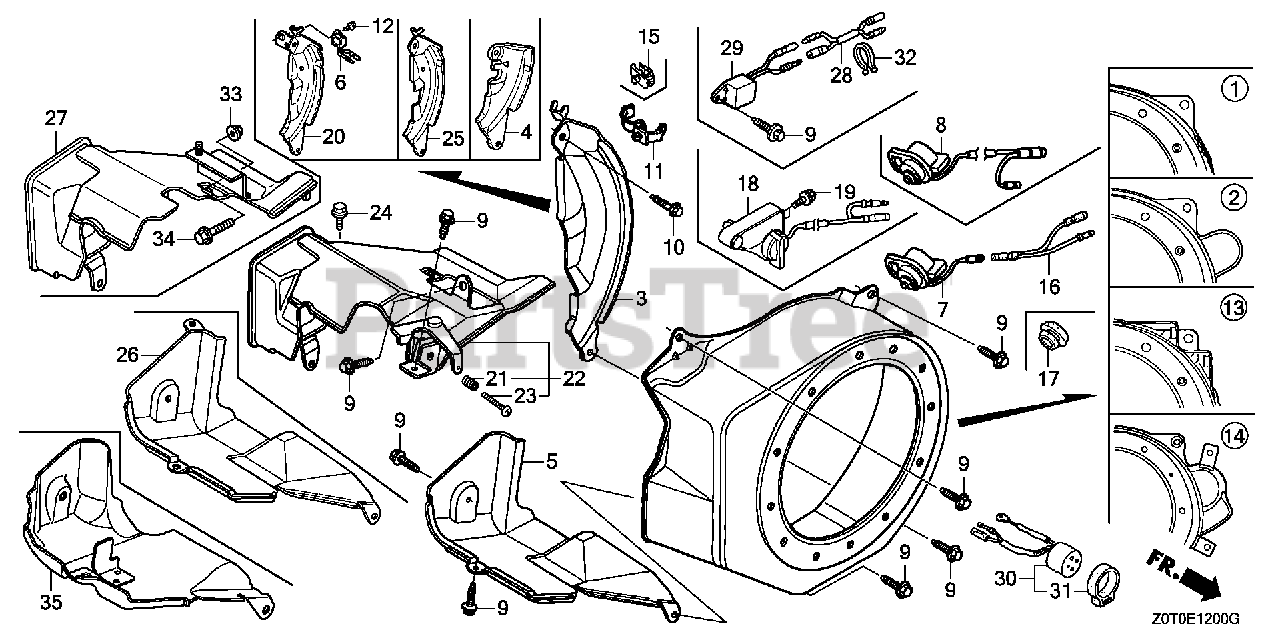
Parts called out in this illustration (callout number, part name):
1	COVER, FAN *R280* (POWER RED)
1	COVER, FAN *NH1* (BLACK)
7	SWITCH ASSY., ENGINE STOP (TOYO DENSO)
7	SWITCH ASSY., ENGINE STOP (MINDA)
9	BOLT, FLANGE (6X12) (CT200)
10	BOLT, FLANGE (6X20) (CT200)
15	CLAMP, CORD
25	PLATE, SIDE (OIL ALERT)
